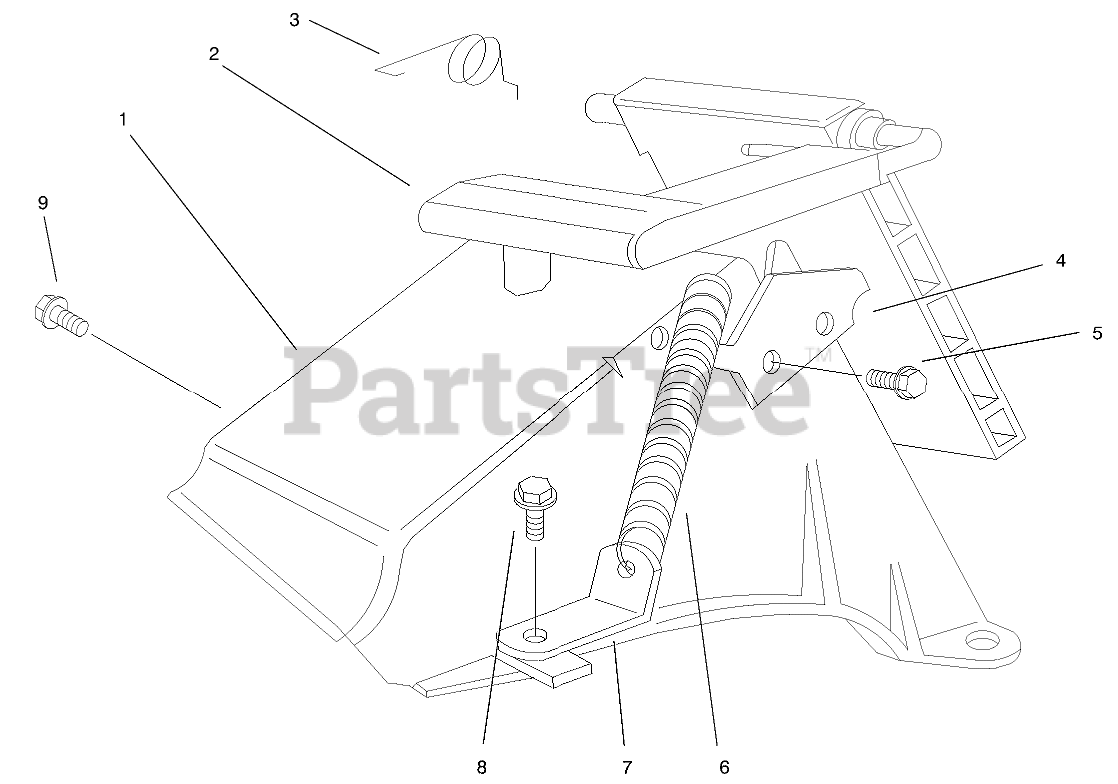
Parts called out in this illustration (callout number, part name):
1	TUNNEL-DISCHARGE
2	DISCHARGE DOOR ASM
3	SPRING-DOOR
4	LATCH-PLATE
5	SCREW-PLASTITE
6	RETAINER-DOOR
7	BRACKET-SPRING
8	SCREW-HWH
9	SCREW AND WASHER ASM
